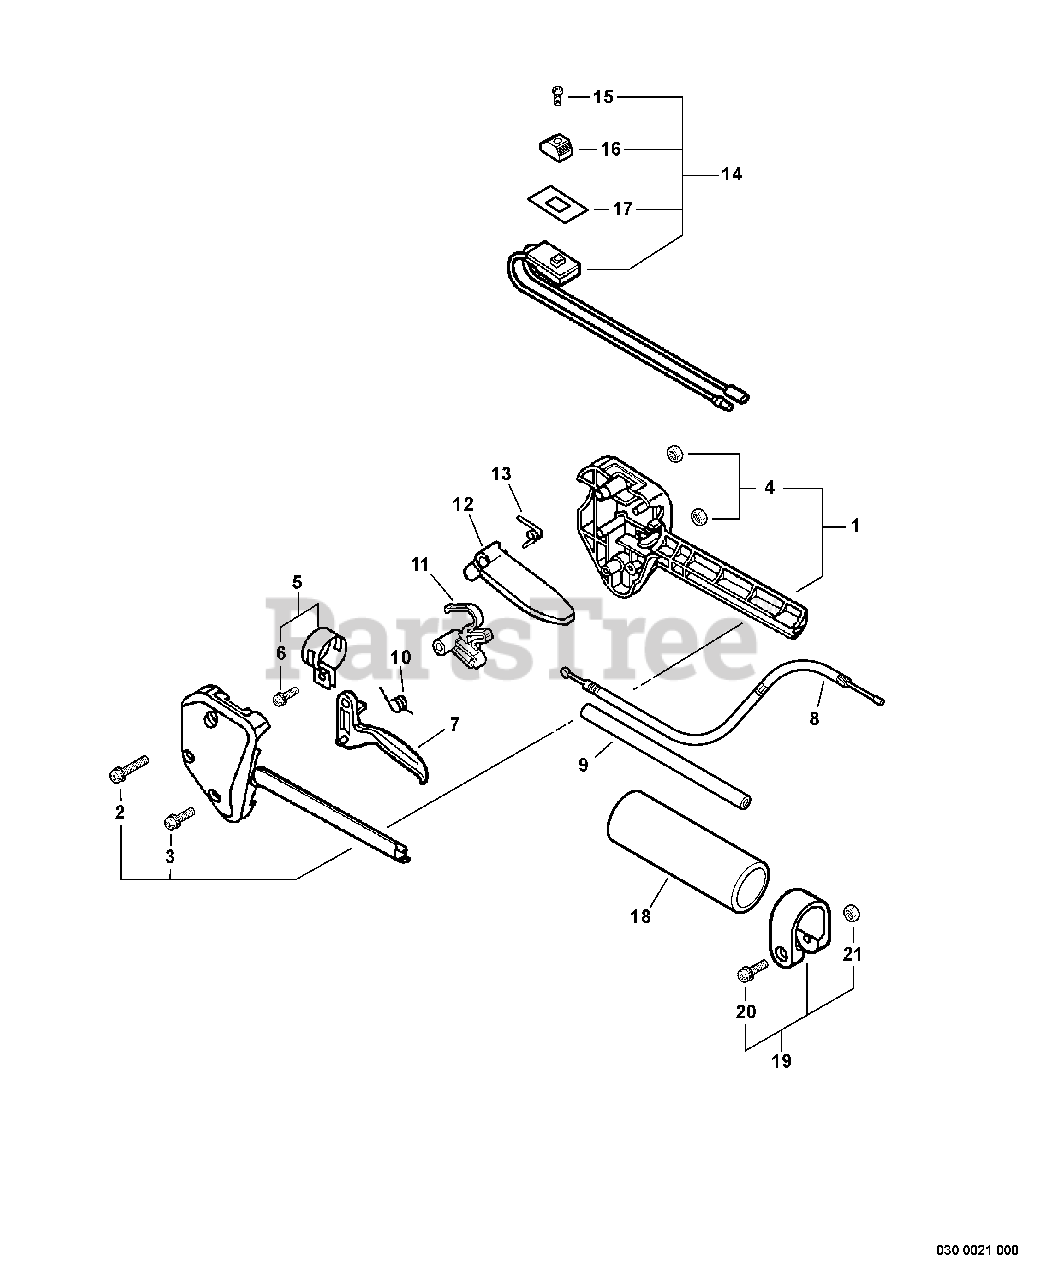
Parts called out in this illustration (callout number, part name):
1	HANDLE KIT, CONTROL
2	SCREW 5×35
3	SCREW 5×25
4	NUT M5
5	CLAMP KIT
6	SCREW 5×14
7	TRIGGER, THROTTLE
8	CABLE, THROTTLE
10	SPRING, TORSION
11	LOCKOUT, THROTTLE
12	LEVER, THROTTLE LOCKOUT
13	SPRING, TORSION
14	SWITCH ASSY, ON-OFF
15	SCREW 3×10
16	KNOB, SWITCH - ORANGE
17	LABEL, SWITCH
18	GRIP, HANDLE
19	CLAMP KIT
20	SCREW 5×28
21	NUT M5
